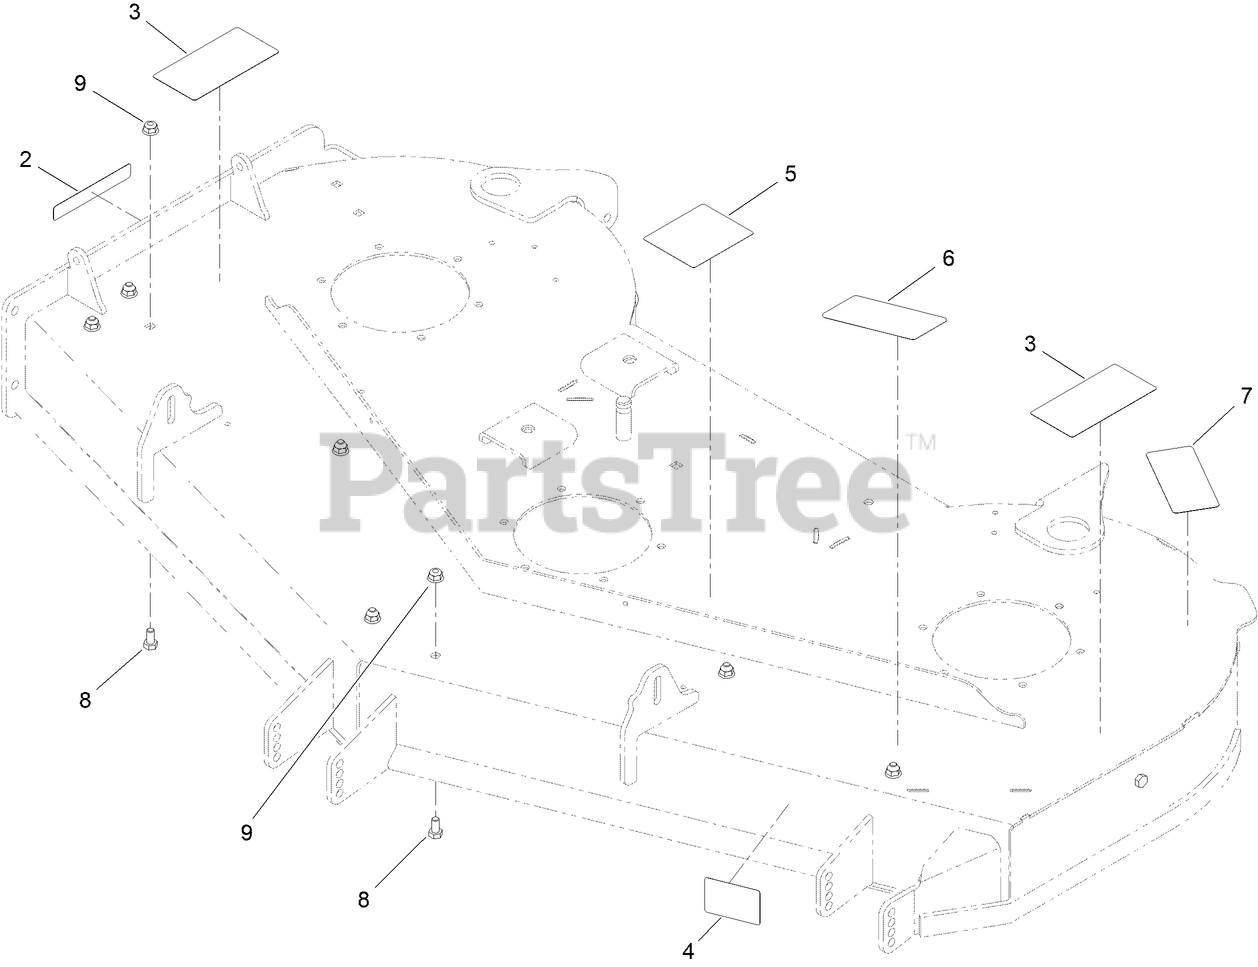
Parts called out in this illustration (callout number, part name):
2	DECAL-DANGER
3	DECAL-DANGER
4	DECAL-SCALP, ANTI
5	DECAL-ROUTING, BELT
6	DECAL-DECK, 54 INCH
7	DECAL-TORQUE, BLADE BOLT
8	SCREW-HH
9	NUT-HF, NI
